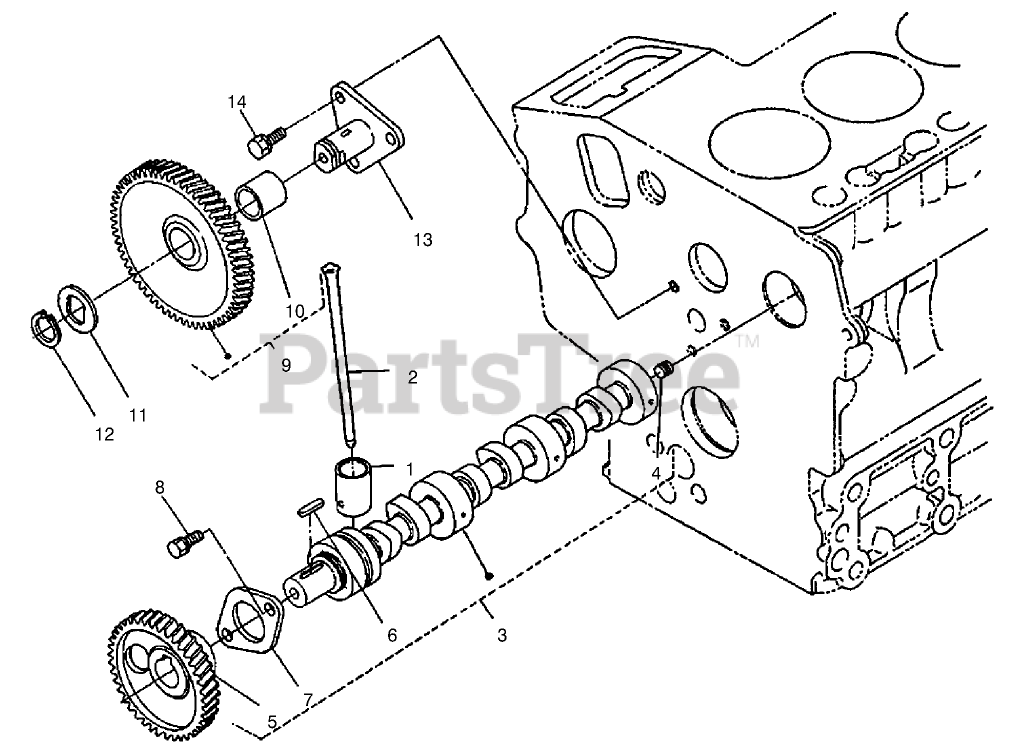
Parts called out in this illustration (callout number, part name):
1	TAPPET
2	ROD-PUSH
3	ASSY CAMSHAFT
4	SCREW-SET
5	GEAR-CAMSHAFT
6	KEY-FEATHER
7	STOPPER-CAMSHAFT
9	GEAR-IDLE
10	BUSHING
11	COLLAR-GEAR, IDLE
12	RING-SNAP
13	SHAFT-GEAR, IDLE
